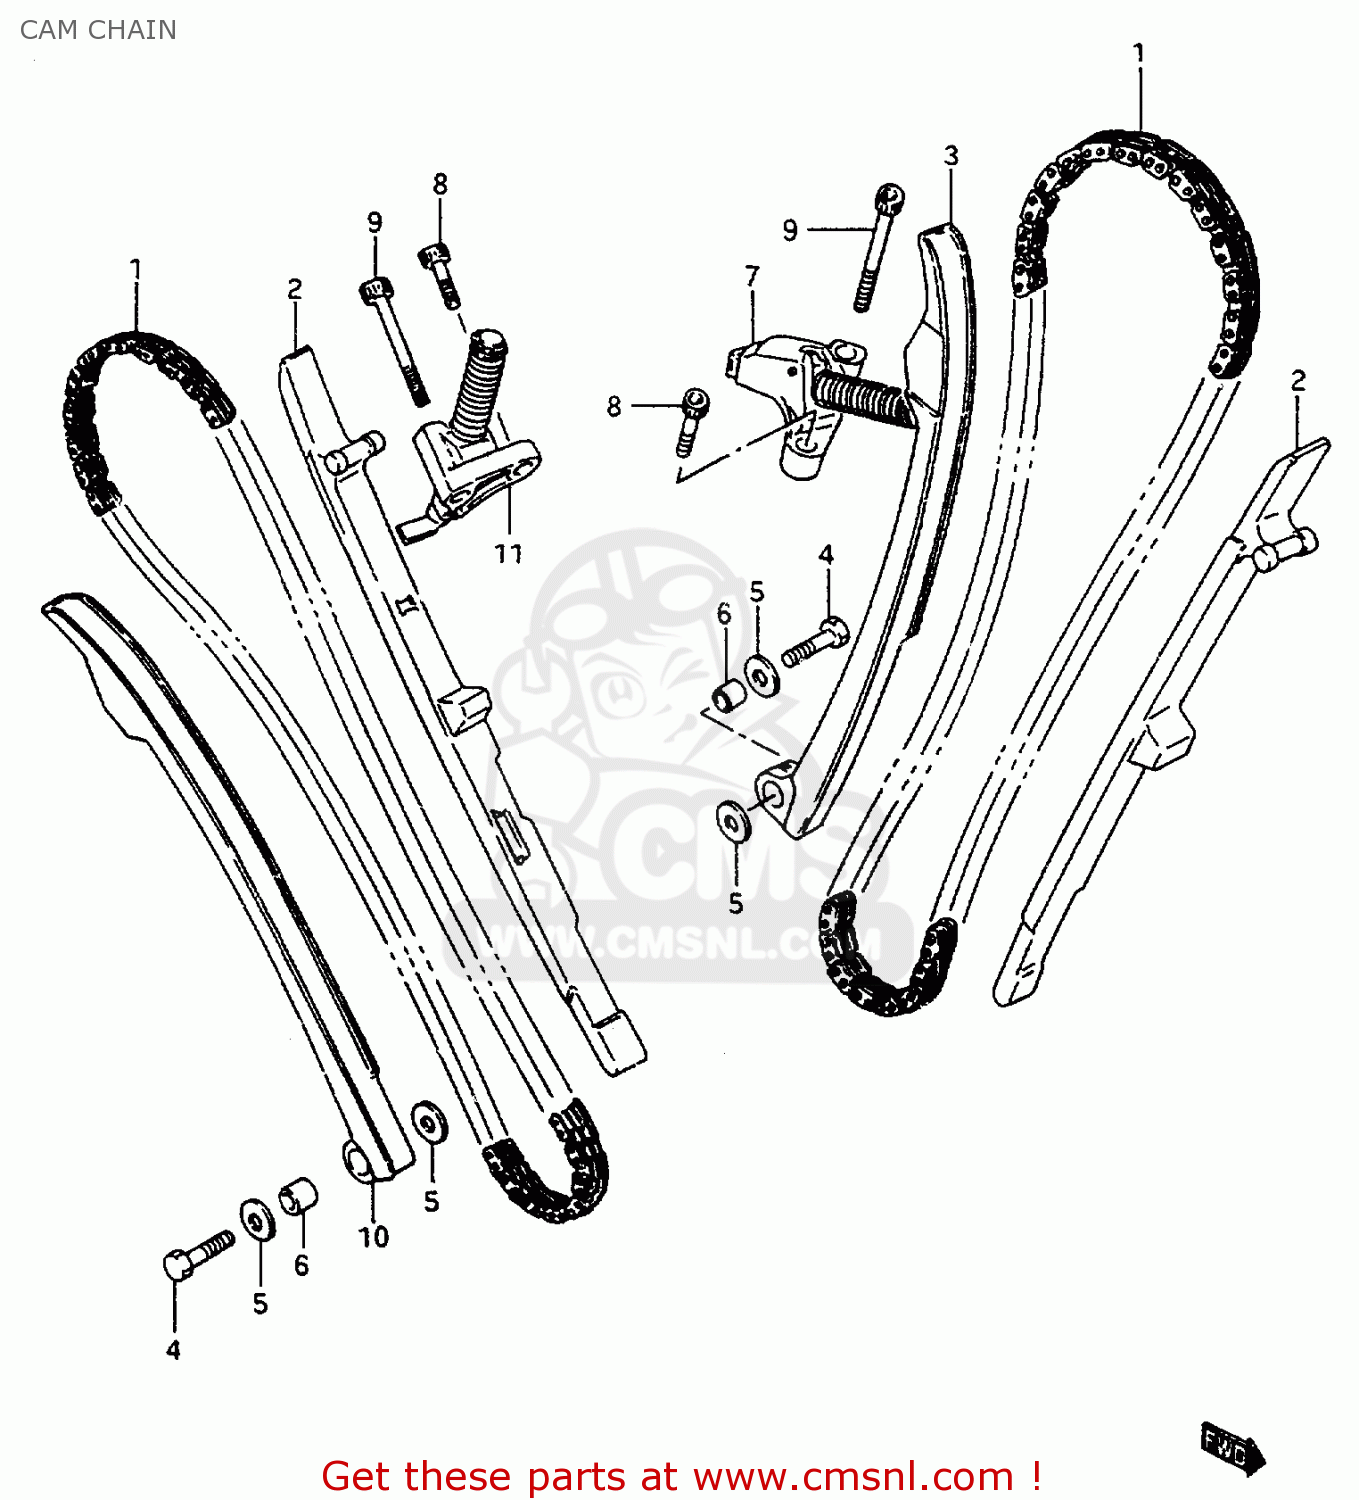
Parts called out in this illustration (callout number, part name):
1	CHAIN,CAMSHAFT DRIVE
2	GUIDE,CAM CHAIN
3	TENSIONER,FR CAM CHAIN
4	BOLT(6X26)
5	WASHER
6	SPACER(6X11X11)
7	ADJUSTER ASSEMBLY,FRONT TENSIONER
8	BOLT,CRKCASE,R
9	BOLT
10	TENSIONER,RR CAM CHAIN
11	ADJUSTER ASSEMBLY,REAR TENSIONER
